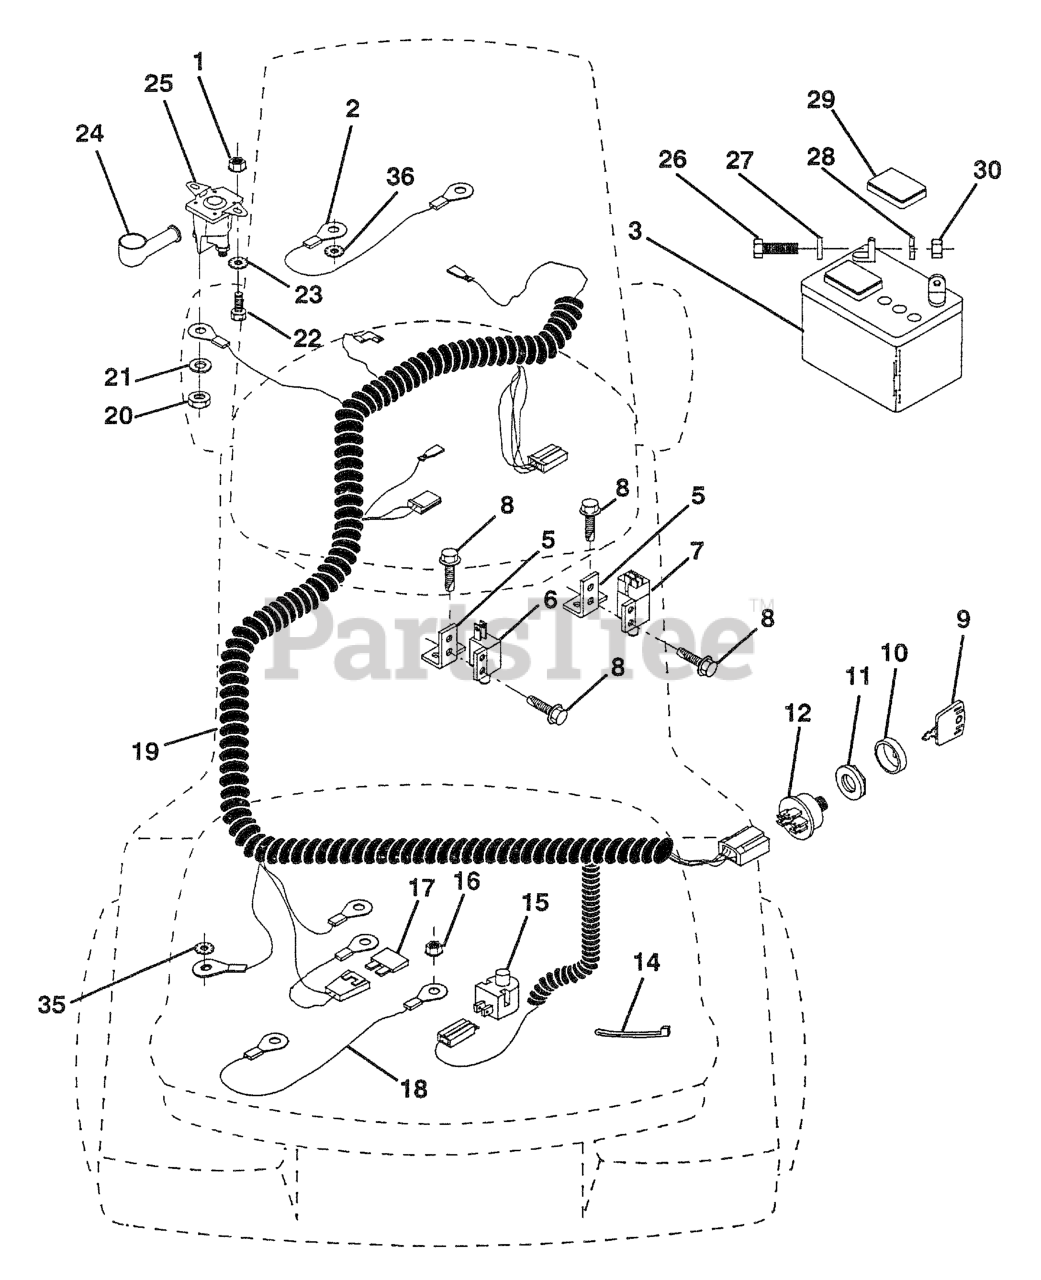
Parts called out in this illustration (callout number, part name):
1	NUT
2	CABLE.BATTERY.6GA.16"RED
3	BATTERY
5	BRACKET LT
6	SWITCH-INTER. GT
7	SWITCH INTERLOCKT
9	KEY.MOLDED.GENERIC
10	COVER KEY IGNITIO
11	NUT IGNITION
12	SWITCH
14	TIE GUIDE
15	RP.SWITCH.PLUNGER.NC.GRAY
16	NUT
18	CABLE ASSY
19	IGNITION HARNESS
20	NUT
21	LOCKWASHER
22	BOLT
23	Washer, Lock Ext. Tooth 1/4
24	TERMINAL COVER
25	SOLENOID KIT
26	BOLT.HEX.1/4.X.3/4.DICHROMATE
27	WASHER
28	LOCKWASHER
29	CAP BATTERY NLA
30	NUT
35	LOCKWASHER
36	Washer Lock Inter. Tooth 1/4
